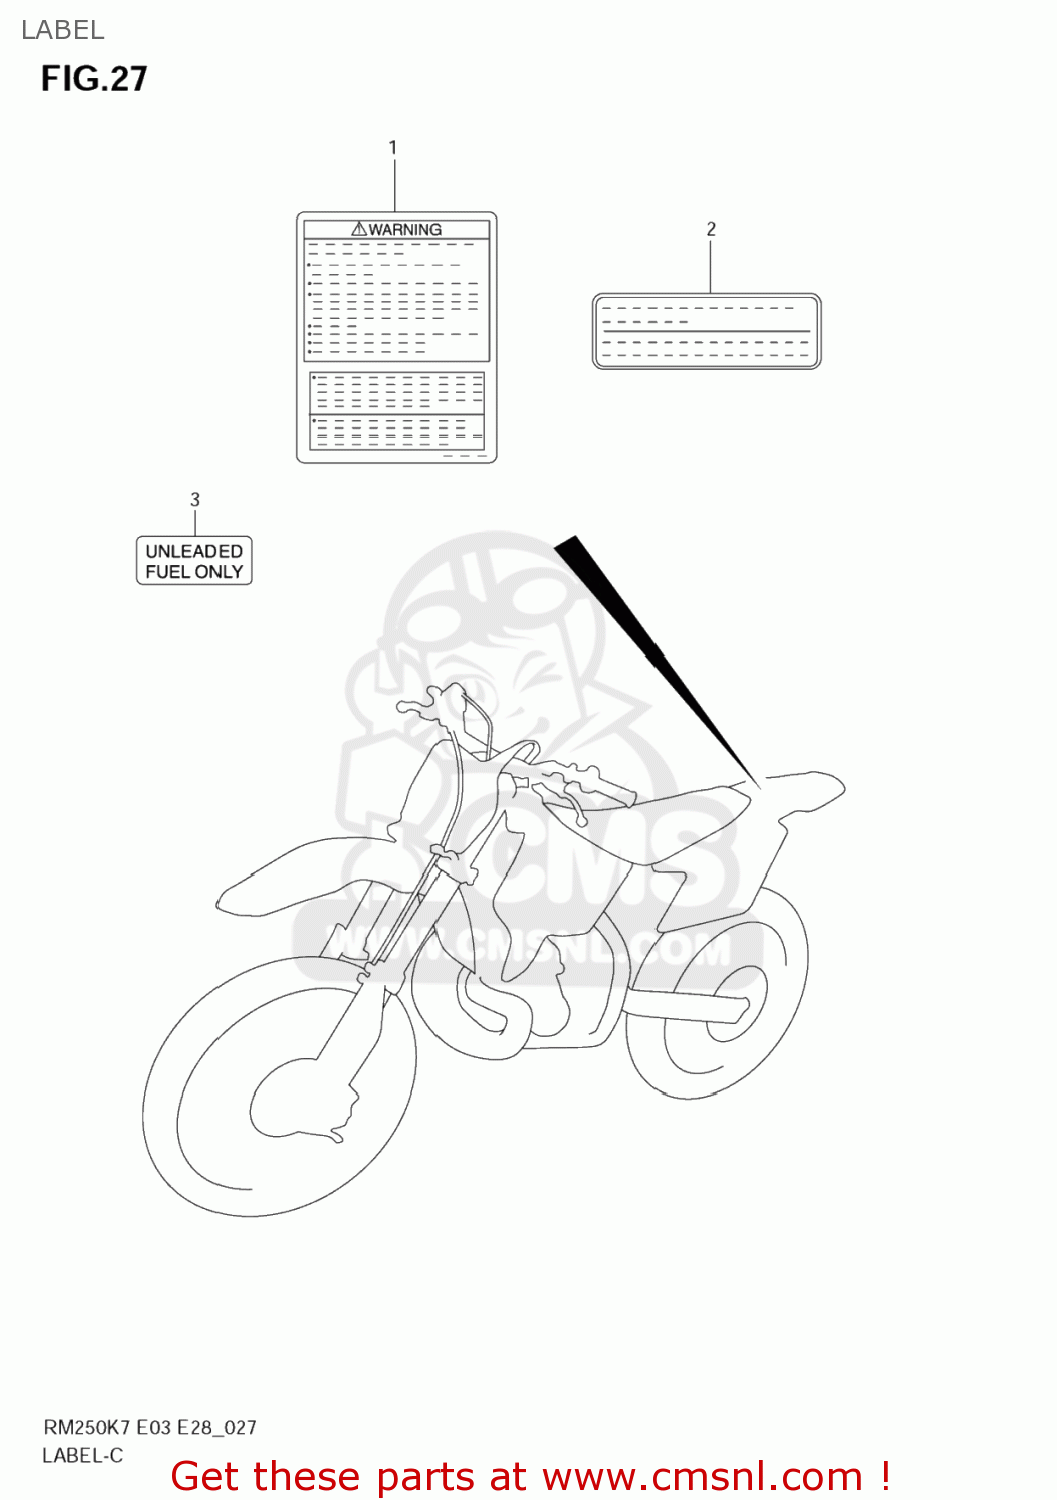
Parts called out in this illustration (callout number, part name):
1	LABEL,WARNING
2	LABEL,WARNING NO.2
3	LABEL,UNLEADED FUEL
4	MANUAL,OWNER'S
